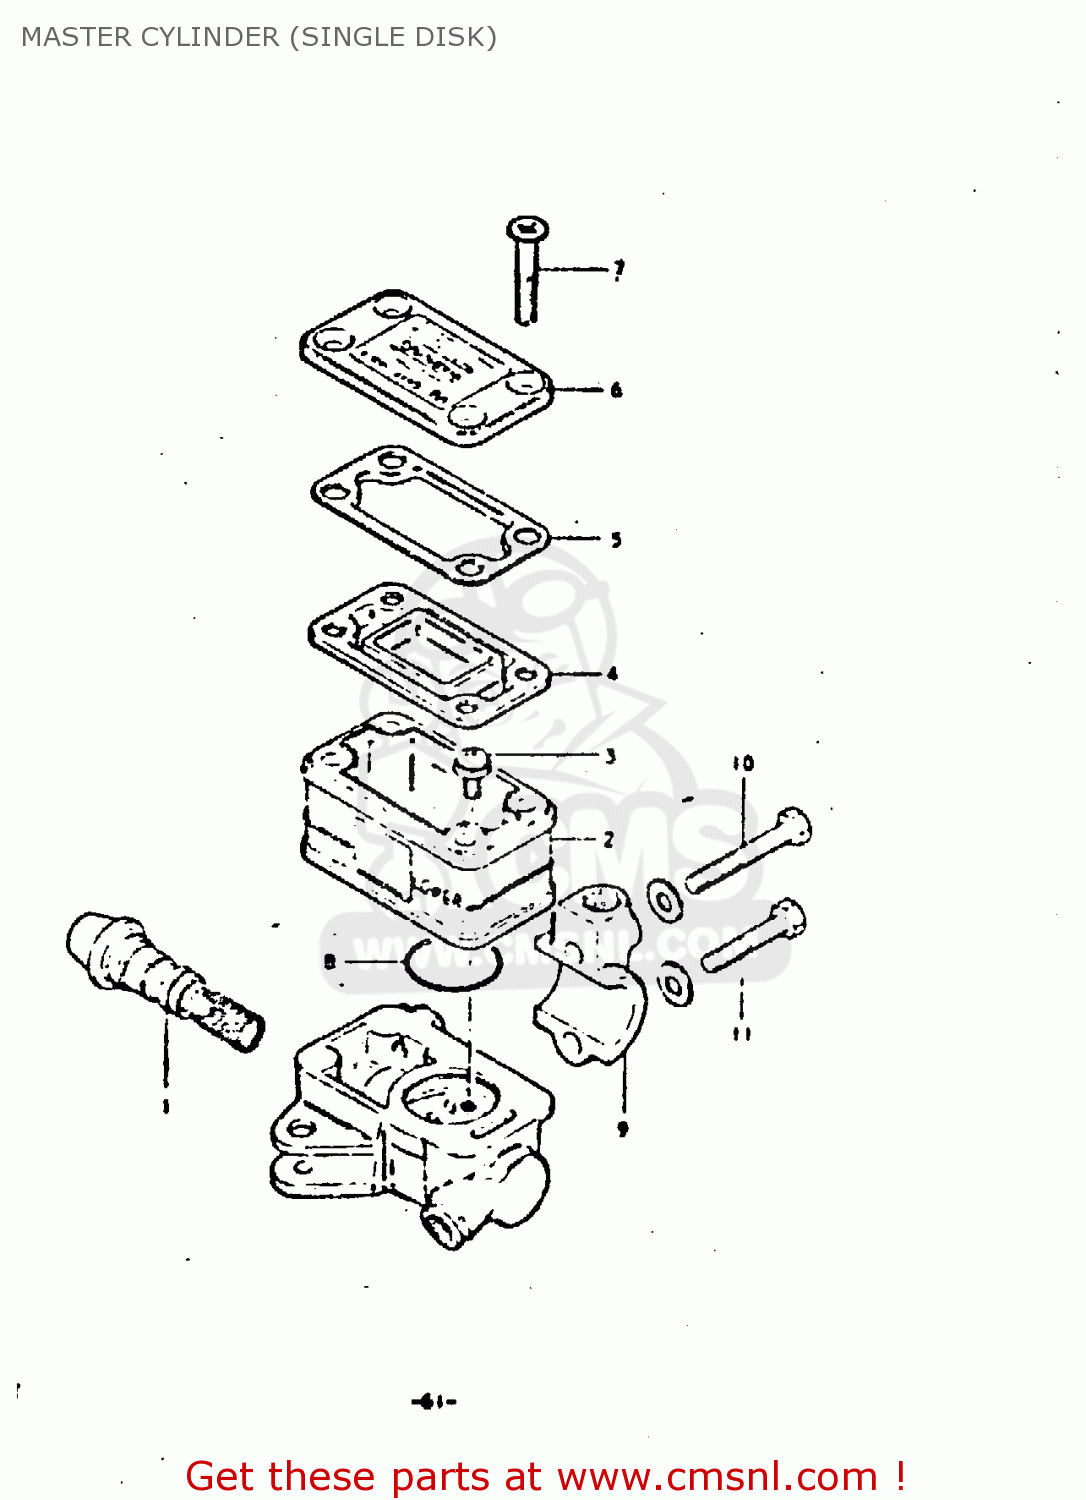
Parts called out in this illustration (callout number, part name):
1	PISTON & CUP SET
2	RESERVOIR
3	SCREW,MASTER C
4	DIAPHRAGM
5	PLATE,DIAPHRAGM
6	CAP
7	SCREW
8	O RING
9	HOLDER
10	BOLT,MASTER CYLINDER H
11	BOLT,MASTER CYLINDER H
